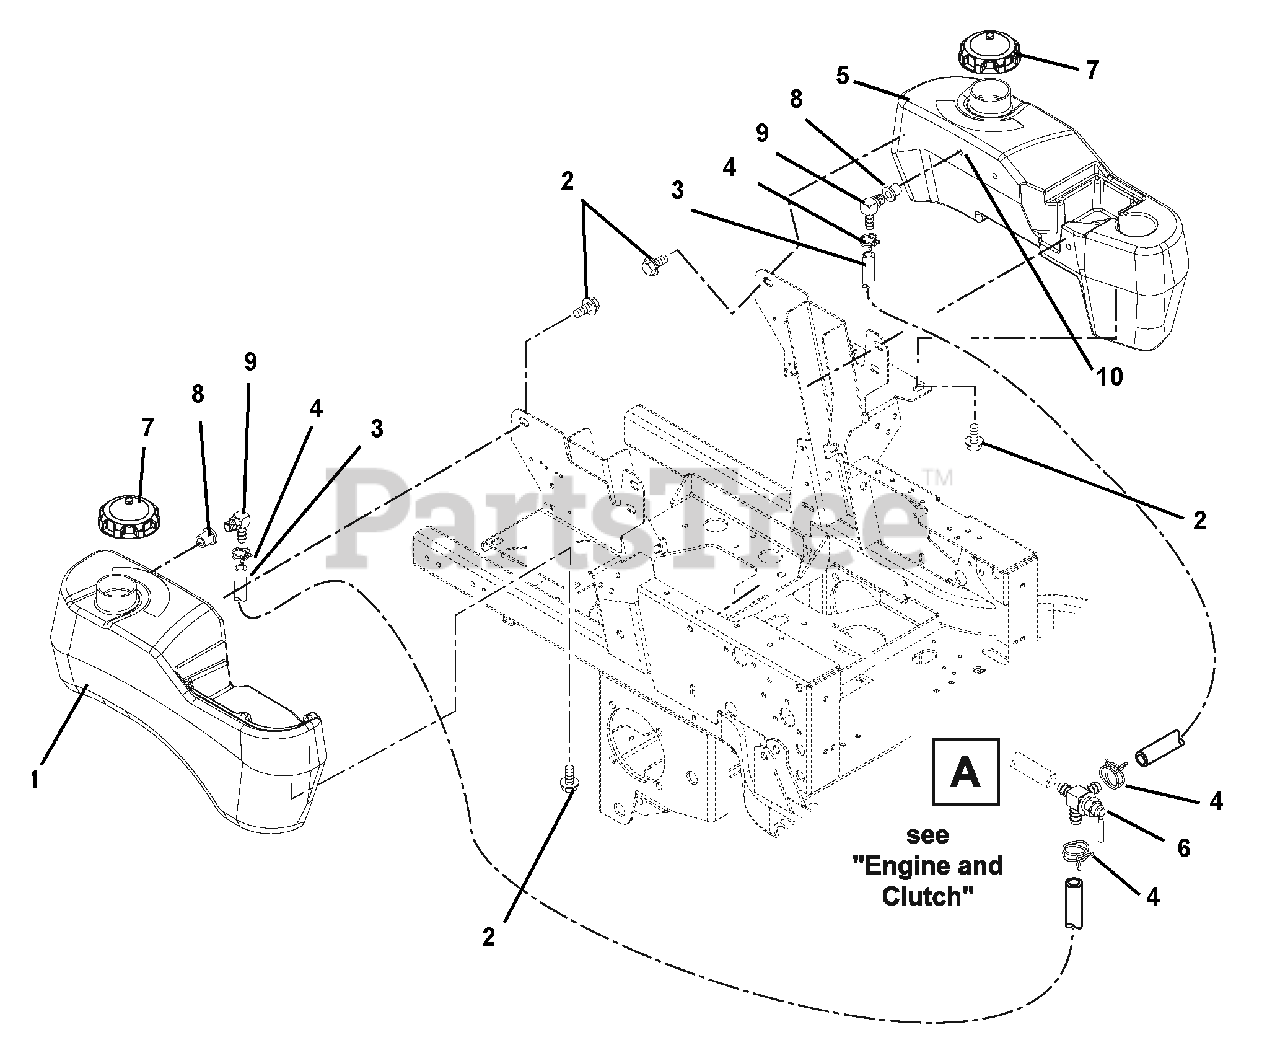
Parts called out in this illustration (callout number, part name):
1	TANK, GAS RH (100 SERIES)
2	BOLT, SEMS .31-18 X .62
3	GAS LINE-BULK 1/4" I.D.
4	CLAMP-HOSE WIRE .490/.510X.116
5	TANK, LH FUEL 100 S. W/O HOSE
6	VALVE, FUEL
7	CAP - FUEL
8	GROMMET, DAPCO VITON #12240
9	FITTING, TANK ELBOW .25 HOSE
10	ASS'Y,MEDIUM TANK FUEL PICK-UP
